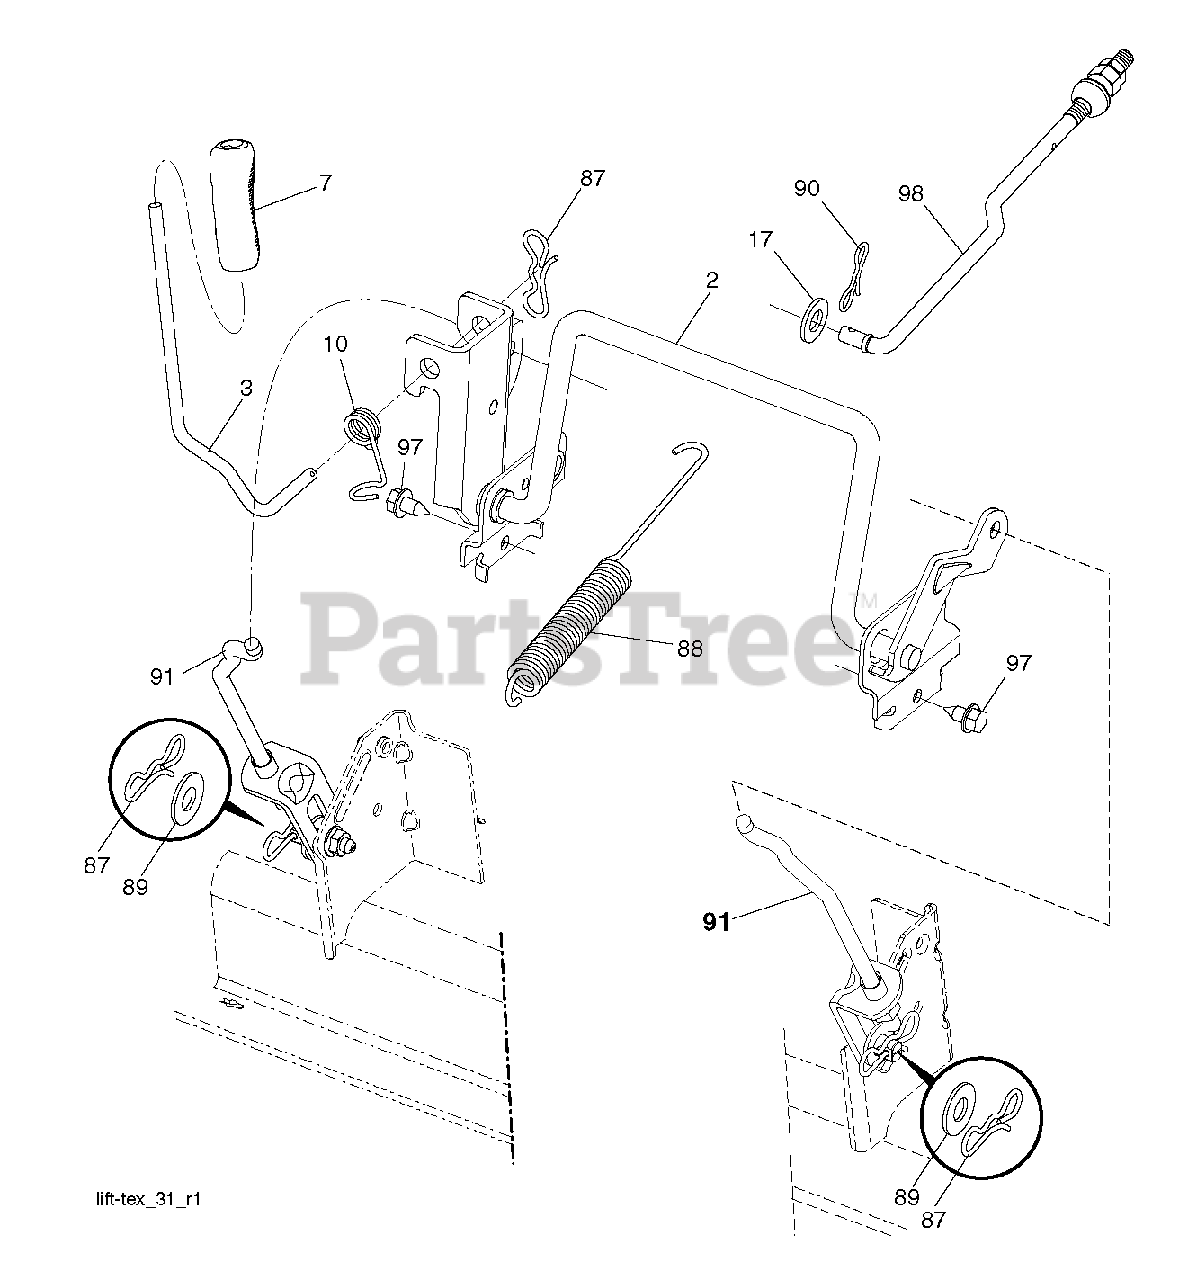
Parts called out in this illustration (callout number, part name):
2	SHAFT LIFT DECK WELD
3	LEVER.LIFT.HANDLE.LT
7	GRIP.HANDLE.LIFT.PVC.BLACK
10	SPRING.TORSION.LIFT.HANDLE
17	WASHER
87	PIN.COTTER.7/16.BOW TI.
88	SPRING.DK.LIFT.97/107.TXCRDII
89	WASHER.CLEAR.ZINC
90	PIN.COTTER.5/16.BOW TI
91	LINK.ASM.LIFT.REAR
98	LINK.ASM.SUSP.FRONT.MW
